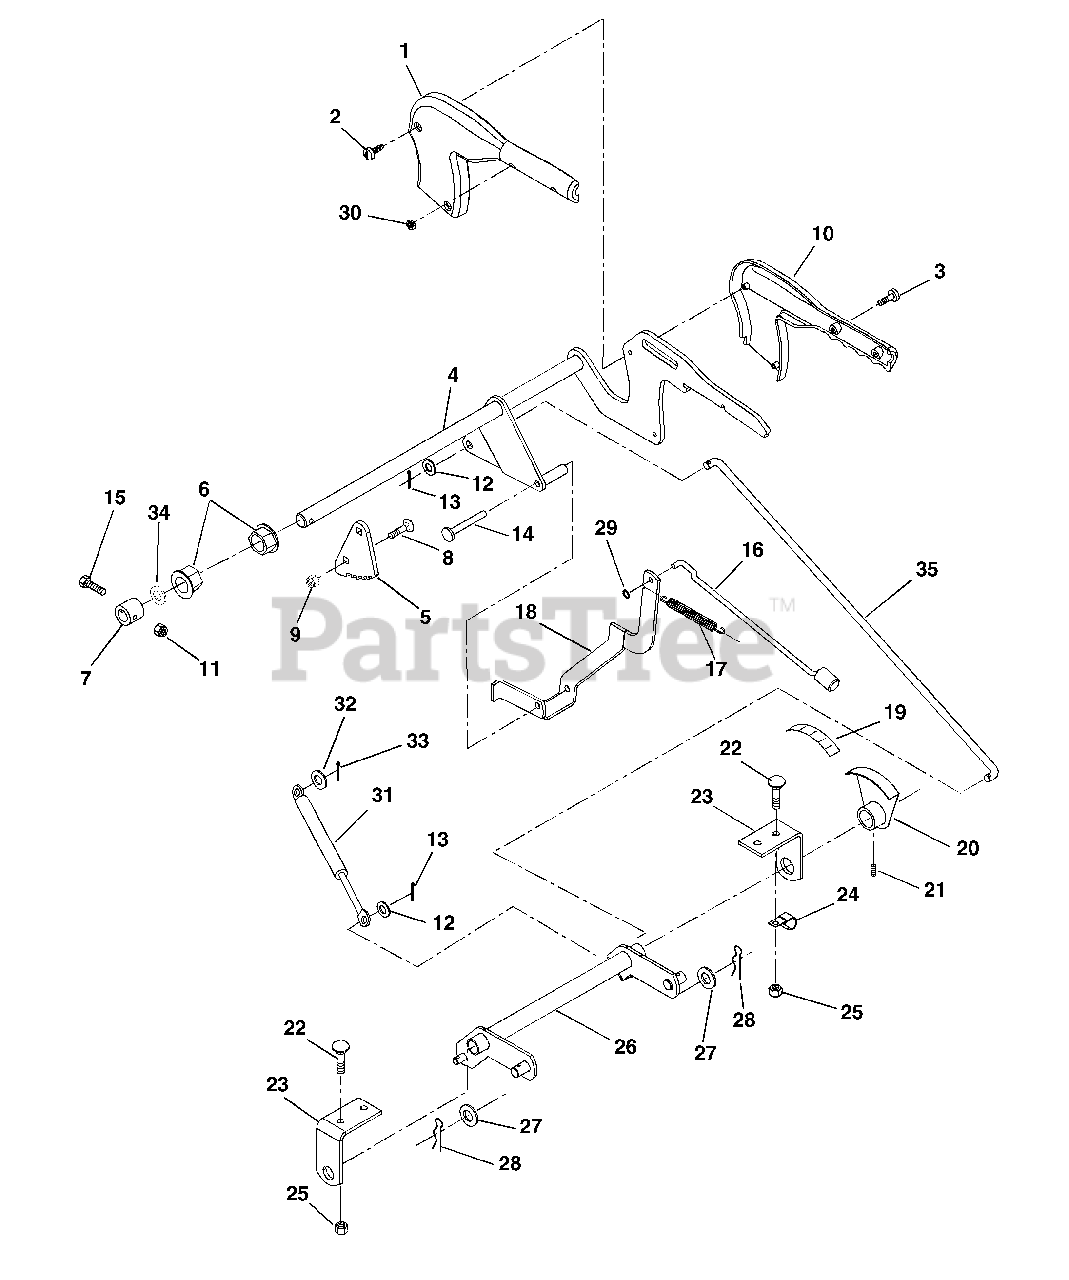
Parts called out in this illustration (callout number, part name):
1	COVER - LIFT RH
2	SCR-TAP 10-16X1.125HI-LOTPHBL
3	SCR-MCH 10-24X.62 P/HD
4	LEVER, LIFT
5	QUADRANT, LIFT
6	BSHG-FLG .750X.873HEXX.53X1.18
7	SPACER-1.25X1.12X.75 W/HOLE
8	@BLT-RDHDSQNK .31-18X.75 G5YZ
9	@NUT-LK-TOP-FLG .31-18 YWZC
10	COVER - LIFT LH
11	@NUT-LK-CTR .25-20 YWZC
12	@WSHR-FL-STL.406X.812X.065 YWZ
13	@PIN-CTR .12X1.00 EXTPRSQCT YZ
14	PIN, PIVOT .312 X 2.56
15	@BLT-HEX .25-20X1.50 GR5 YWZC
16	PIN, LIFT
17	SG-TENS .048X.44X2.25 WLD 9
18	LEVER, DETENT
19	DECAL, INDICATOR
20	INDICATOR, DECK HEIGHT(ASSY.)
21	SCR-SET .25-20X.25 SKHCUP OH
22	BLT-RHHDSQSHNK .38-16X.75 G2YZ
23	BRACKET, CENTER LIFT
24	J-CLAMP
25	@NUT-SPNLK-FLG .375-16 YWZC
26	LEVER, CENTER LIFT
27	WSHR-FL-STL .630X1.005X.062 YZ
28	PIN-HAIR-EXT .12X.31X2.37 YWZC
29	RG-RTNG-EXT .250X.010
30	NUT,10-24 LOW CROWN, ACORN
31	SPRING, 150# GAS
32	@WSHR-FL-STL.38X.875X.083 YWZC
33	PIN-HAIR INT .08X.18X1.18 YWZC
34	@WSHR-FL-STL.812X1.50X.135YWZC
35	LINK, LIFT
